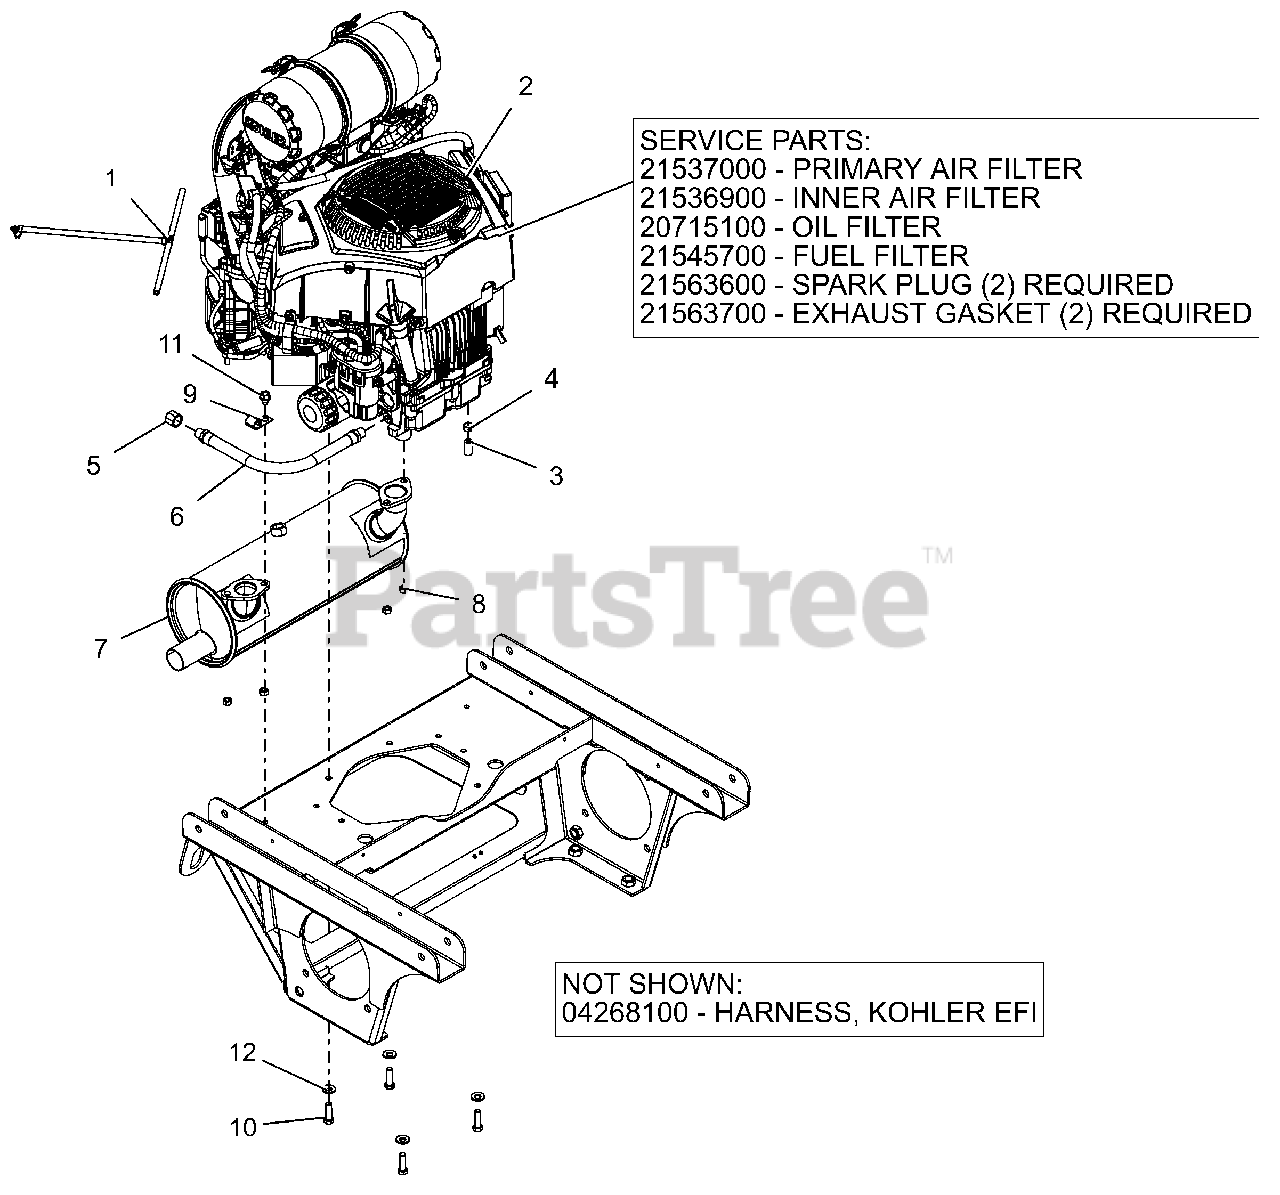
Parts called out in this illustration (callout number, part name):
1	ASM, KOHLER EFI VAPOR LINE
2	ENGINE, KOHLER EFI
2	ELEMENT, OUTER PRIMARY
2	ELEMENT, INNER SAFETY
2	OIL FILTER KOHLER
2	FILTER-FUEL KOHLER COURAGE PRO
2	PLUG, SPARK
2	GASKET, EXHAUST
3	HOSE, .25 LOW-PERM BULK GAS
4	CLAMP, FUEL LINE
5	PIPE CAP 3/8 NPT FEMALE
6	HOSE,HYD .38-14-0K M6N0-M6N0
7	MUFFLER, KOHLER EFI
8	NUT-LK-TOP M8-1.25 YWZC
10	BLT-HEX.38-16X1.25 G5YZ NYTORQ
11	@SCR-TAP .38-16X.50 HWH TR YWZ
12	WASHER, 3/8" SPRING DISC
